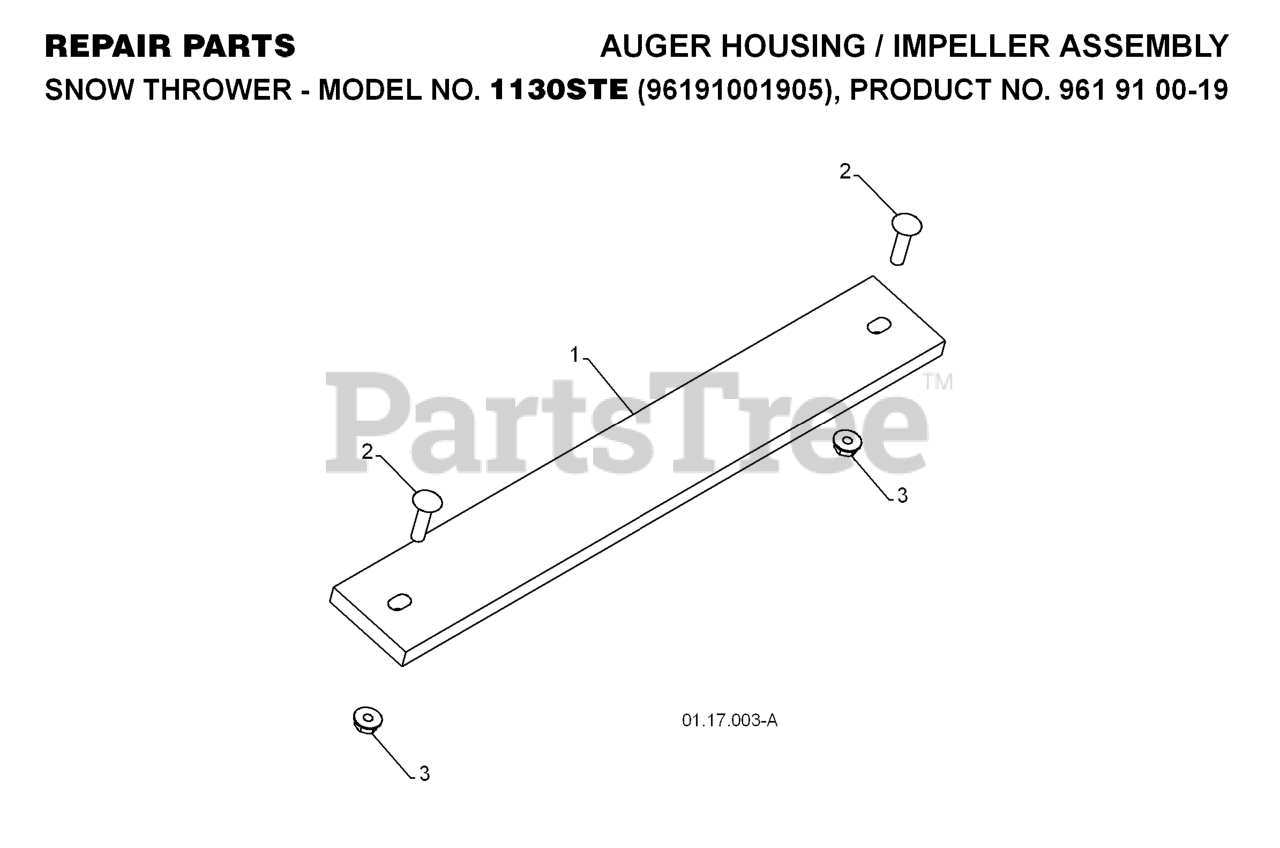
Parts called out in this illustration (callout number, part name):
1	WEIGHT AUGER HOUSING 30
2	BOLT.CARRIAGE.5/16-18
3	NUT.LOCK.5/16-18
